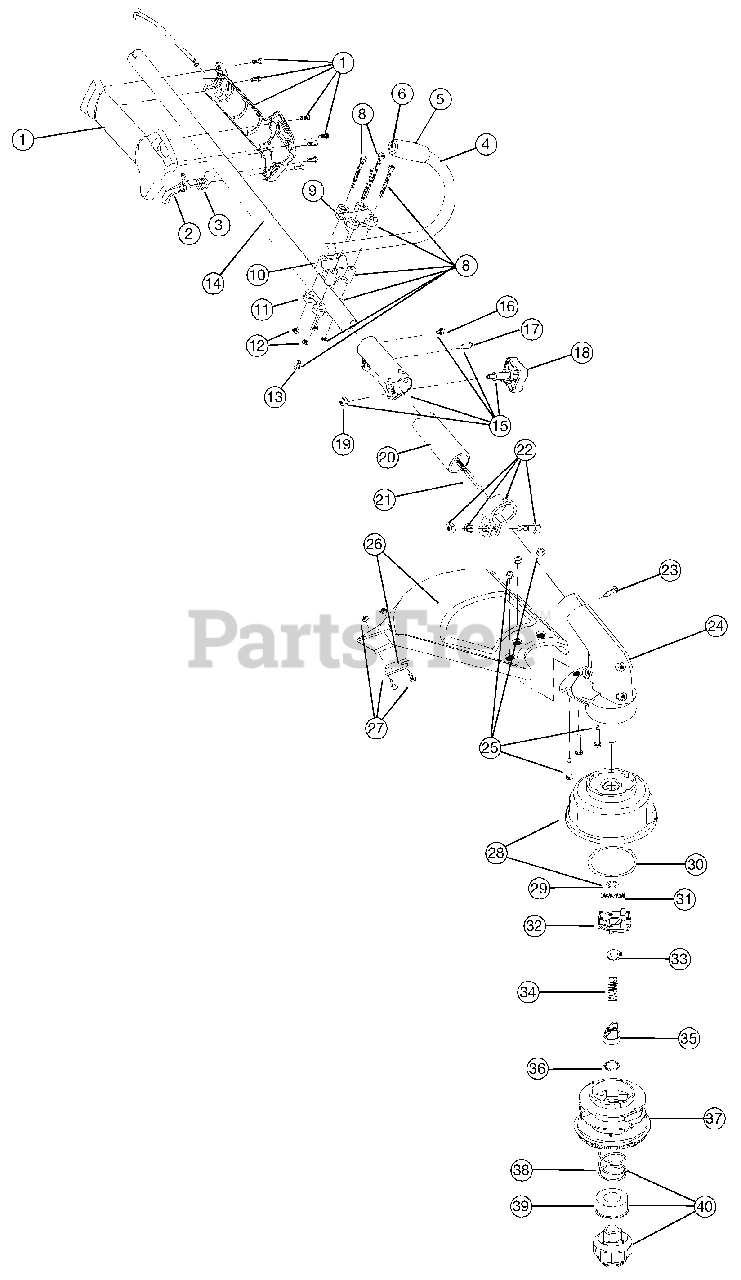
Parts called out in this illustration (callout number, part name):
1	Throttle Housing Assembly
2	Throttle Trigger
3	Throttle Trigger Spring
4	J-Handle Assembly
6	Tube Closure
7	Handle Bracket Assembly
9	Upper Handle Clamp
10	Middle Handle Clamp
11	Lower Handle Clamp
13	Anti-Rotation Screw
14	Upper Drive Shaft Housing Assembly
15	EZ-Link(TM) Coupler
18	Adjustment Knob
19	Knob Retaining Nut
20	Lower Drive Shaft Housing Assembly
21	Lower Flexible Drive Shaft
22	Lower Clamp Assembly
23	Anti-Rotation Screw
24	Gearbox Assembly
25	Shield Mounting Hardware
26	Shield and Blade Assembly
27	Blade Assembly
28	Outer Spool Assembly
29	Retainer
30	Thrust Washer
31	Small Spring
32	Slider
35	Plunger
37	Inner Reel
38	Large Spring
39	Foam Seal
40	Bumb Head Knob Assembly
